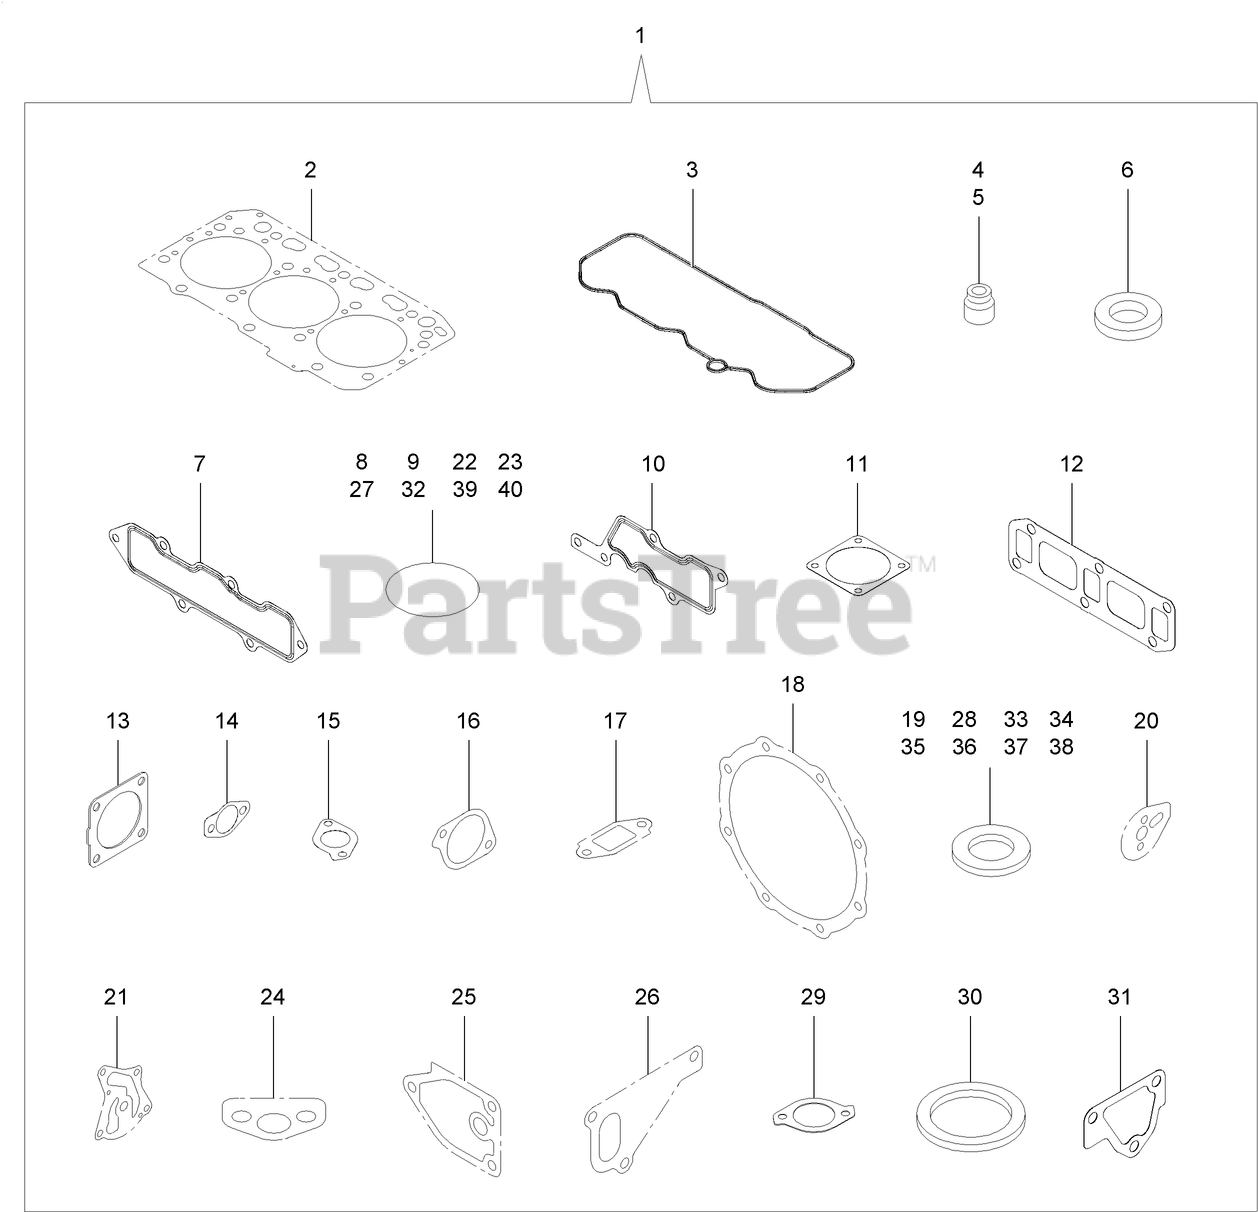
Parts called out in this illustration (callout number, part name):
1	PACKING (GASKET SET)
2	HEAD GASKET ASM
3	GASKET-HEAD, CYLINDER
4	SEAL-STEM, VALVE
5	SEAL-STEM, VALVE
6	GASKET-INJECTOR
7	GASKET-MANIFOLD, INTAKE
8	O RING-SENSOR, PRESSURE
9	O-RING
10	GASKET-COLLECTOR
11	GASKET-THROTTLE
12	GASKET-MANIFOLD, EXHAUST
13	GASKET-SILENCER
14	GASKET-COOLER, E G R
15	GASKET
16	GASKET-INTAKE VALVE, E G R
17	GASKET-OUT VALVE, E G R
18	GASKET-D P F
19	GASKET-SENSOR
20	GASKET-IDLE, SHAFT B
21	GASKET
22	O-RING
23	O-RING
24	GASKET
25	GASKET
26	GASKET
27	O-RING
28	GASKET
29	GASKET
30	GASKET
31	GASKET
32	O-RING
33	WASHER-SEAL
34	WASHER-SEAL
35	WASHER-SEAL
36	WASHER-SEAL
37	GASKET
38	GASKET
39	O-RING
40	O-RING
